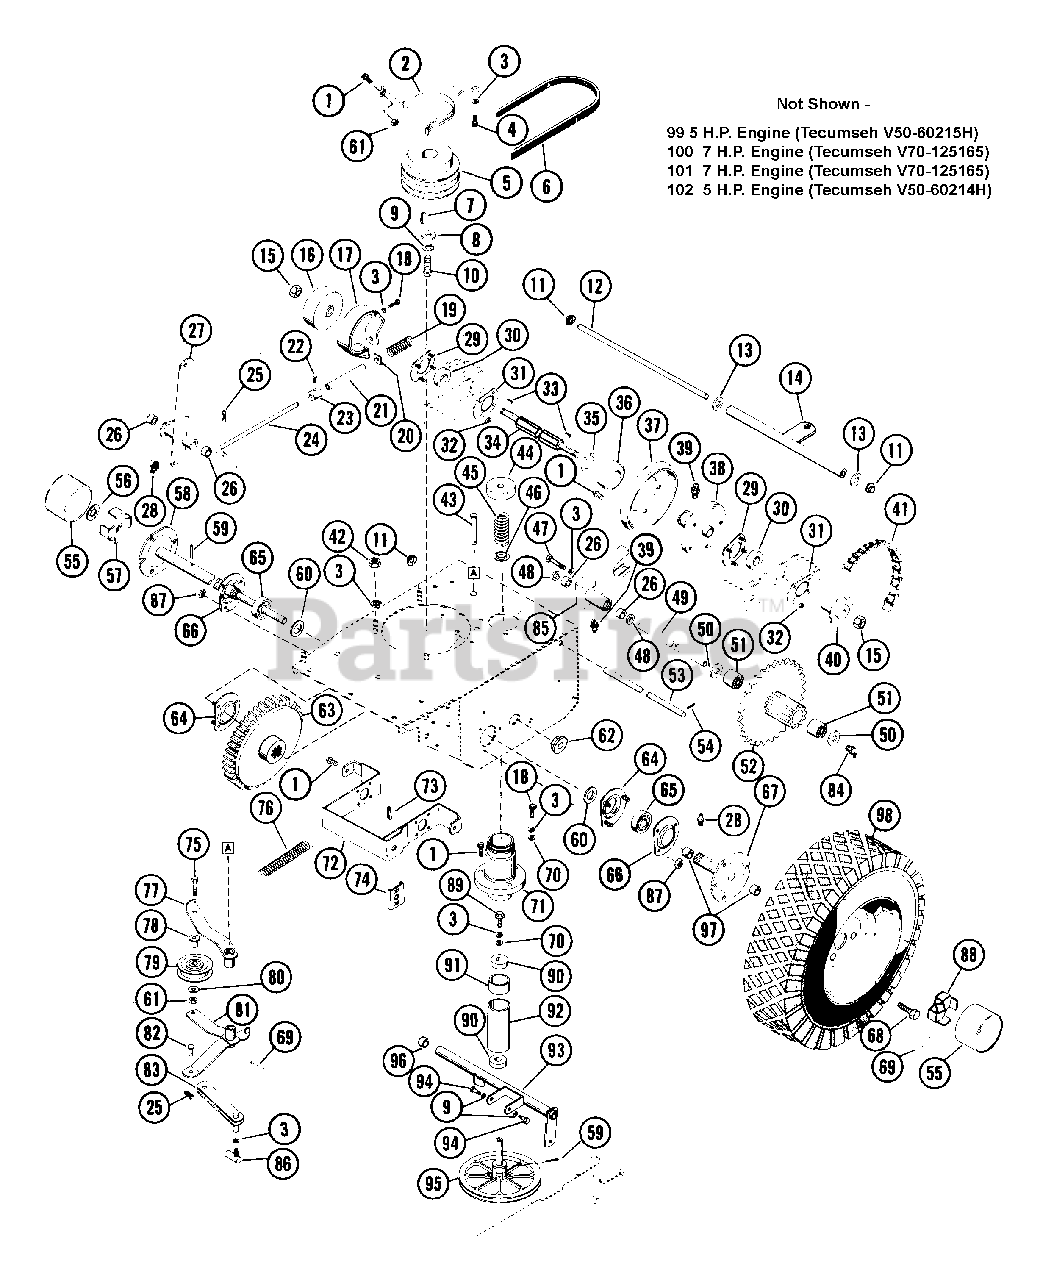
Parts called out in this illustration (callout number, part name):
1	BLT-SERHFWH .31-18X.50 PL
2	REAR BELT FINGER
3	WSHR-LK .312X.097 PL HVY
4	BLT-HEX .31-18X1.00 PL GR 2
5	ENGINE SHEAVE
6	V-BELT, SAE 380-RAW EDGE
7	KEY-WDRF .156X.625X.25 SAE 6
8	WSHR-FL-STL .438X1.125X.19
9	WSHR-LK .375X.115 HVY PL
10	BLT-HEX .38-24X1.25 BLKO GR5
11	CAP, .50 ROD YWZC
12	HITCH SHAFT
13	WAVE WASHER .531X.781X.125FH
14	HITCH
15	NUT-LK-CTR .50-20 PL
16	BRAKE DRUM
17	BRAKE BAND
18	BLT-HEX .31-18X.50 PL GR2
19	SG-COMP .102X.85X1.031
20	BRAKE BAND WASHER
21	BRAKE SPACER .5 X .4 X 2.63
22	SCR-SET .25-20X.50 SQHCUP HT
23	SET COLLAR
24	BRAKE ROD
25	PIN-COTR .09X.75 PL
26	BSHG-SLV .625X.750X.500 BR
27	CLUTCH BRAKE BELL CRANK
28	HYDRAULIC DRIVE FITTING
29	BEARING FLANGE
30	BRG-BALL .500X1.38X.437
31	BEARING FLANGE
32	NUT-KEPS 10-24 PL
33	KEY-WDRF .125X.625X.250 SAE5
34	HEX SHAFT
35	RG-RTNG-EXT 1.250X.050
36	BRG-BALL 1.25X2.18X.63
37	FRICTION DISC
39	ZERK FITTING
40	9 TOOTH SPROCKET
41	CHAIN
42	NUT-HEX .312-18
43	PIN-CLEVIS .500 X 3.250
45	SG-COMP .148X1.23X2.53 WLD87
46	SPRING RETAINER
47	BLT-HEX .31-24X.50 GR5
48	SEAL .625X.875X.125
49	CARRIER SHAFT
50	WSHR-FL-STL .630X1.005X.062 PL
51	BRG-NEEDLE .625X.812X.50
52	PINION ASSEMBLY
53	DISC FORK ROD
54	PIN-ROLL .188X1.00
55	HUB CAP
56	PUSHNUT
57	SPINDLE CUP
58	R H AXLE SHAFT
59	PIN-ROLL .188X1.25
60	WSHR-FL-STL .880X1.380X.062
61	NUT-LK .312-18 GR A PL
62	FLANGE BUSHING
63	DIFFERENTIAL ASSEMBLY
64	BEARING FLANGE
65	BRG-BALL .876 X 1.750 X .50
66	BEARING FLANGE
67	L H AXLE ASSEMBLY
68	BLT-WHL .50-20X.75 GR5 PL
69	PIN-COTR .12X1.0 PL
70	WSHR-FL-STL.312X.734X.065PL
71	DRIVE SPRING HOUSING
72	CARRIER
73	PIN-ROLL .188X1.50
74	LOCATING PLATE
75	BLT-HEX .31-18X1.25 PL GR2
76	SG-TENS .063X.44X2.81 WLD 18
77	IDLER ARM
78	SPCR, BRG .315X.50X.688X.281
79	IDLER
80	WSHR-FL-STL .38X.875X.083 PL
81	SHIFT TRANSFER LEVER
82	CLEVIS PIN
83	SHIFT LINK
84	FRAME CHANNEL
85	SLIDING FORK ASSEMBLY
86	BALL JOINT
87	NUT-LK-FLG .250-20 PL
88	SPINDLE CUP
89	BLT-LK .31-18X.75 GR 5
90	BRG-BALL .625X1.375X.44
91	BEARING SPACER .87 X .63 X 1.2
92	DRIVE SPINDLE HOUSING
93	DISK FORK
94	SCREW PIN
95	DRIVE DISK ASSEMBLY
96	FORK SPACER
97	BSHG-SLV .562X.625X.625 BRZ
97	TIRE & WHEEL ASSEMBLY
97	WHL 6 IN O.D.
97	TIRE 6 X 4.10/3.50
97	TUBE
98	TURF SAVER TIRE & WHEEL ASSEMB
98	TIRE 13/6.50 X 6
98	WHL
98	TUBE
99	5 H.P. Engine(Tecumseh V50-60215H) orreplacement
100	7 H.P. Engine(Tecumseh V70-125165) orreplacement
101	7 H.P. Engine(Tecumseh V70-125156) orreplacement
102	5 H.P. Engine(Tecumseh V50-60214H) orreplacement
